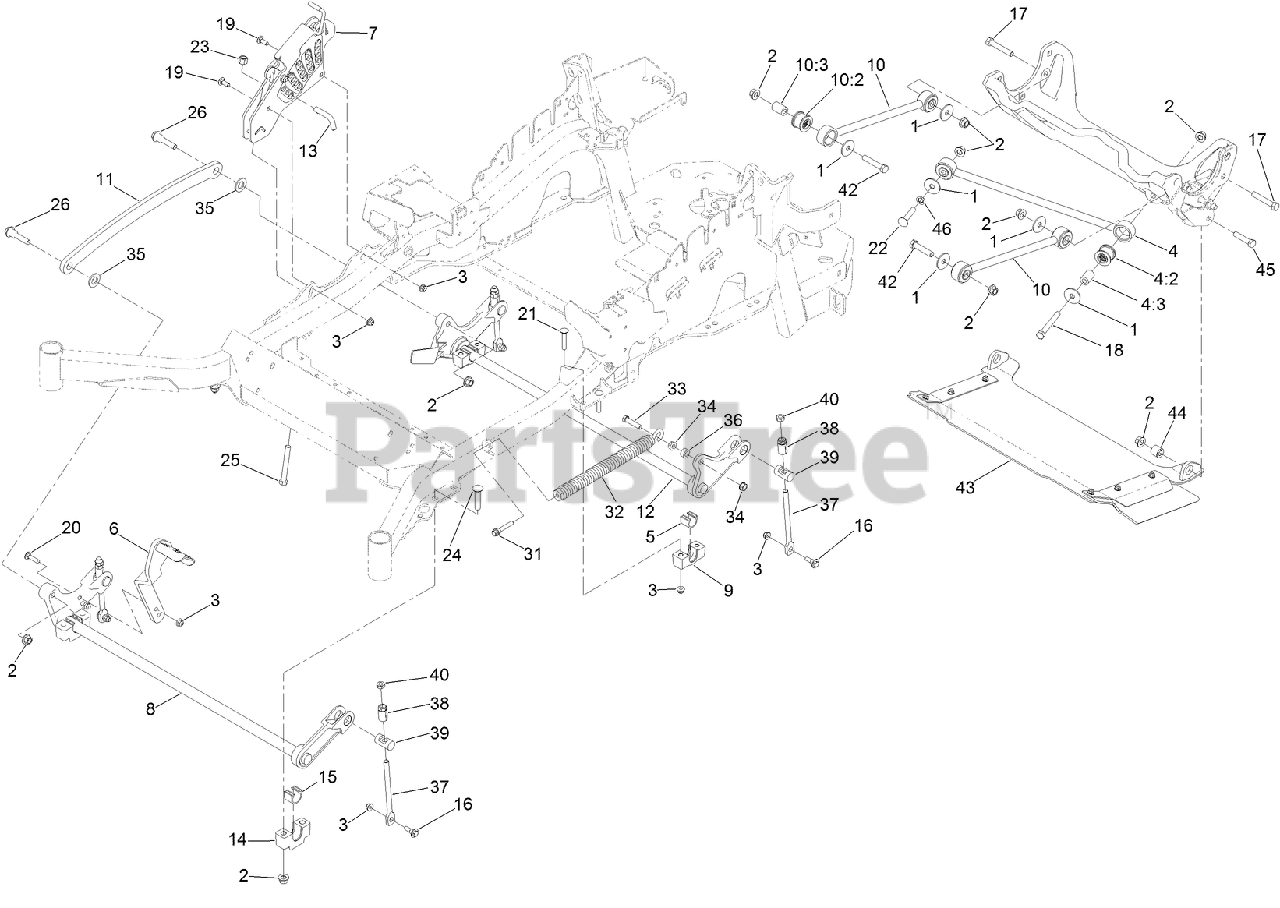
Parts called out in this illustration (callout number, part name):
1	WASHER-THRUST
2	NUT-LOCK
3	NUT-HF, NI
4	PANHARD ROD ASM
4:2	BUSHING-SUSPENSION, RUBBER
4:3	SPACER
5	BEARING-CROSS SHAFT, REAR
6	LEVER-FOOT
7	HEIGHT-OF-CUT ASM
8	DECKLIFT-FRONT
9	SUPPORT-CROSS SHAFT, BEARING REAR
10	DECK STRUT ASM
10:2	BUSHING-SUSPENSION, RUBBER
10:3	SPACER
11	LINK-LIFT, DECK
12	LIFT-DECK, REAR
13	PIN-HOC
14	SUPPORT-CROSS SHAFT, BEARING
15	BEARING-CROSS SHAFT, FRONT
16	SCREW-SHOULDER, HHF
17	SCREW-HH
18	SCREW-HH
19	BOLT-CARR
20	SCREW-CARR
21	SCREW-CARR
22	SCREW-CARR
23	NUT-LOCK, NI
24	BOLT-CARR
25	BOLT-TAP
26	SCREW-HHF, SHOULDER
31	BOLT-SHOULDER
32	SPRING-EXTENSION
33	SCREW-HH
34	NUT-HF
35	WASHER-FLAT
36	SPACER
37	LINK-ADJUSTER, DECK LIFT
38	ADJUSTER-LIFT, DECK
39	TRUNNION
40	NUT-JAM
42	SCREW-HH
43	DISCHARGE TUNNEL ASM
44	BUSHING-SLEEVE
45	SCREW-HH
46	NUT-PUSH
